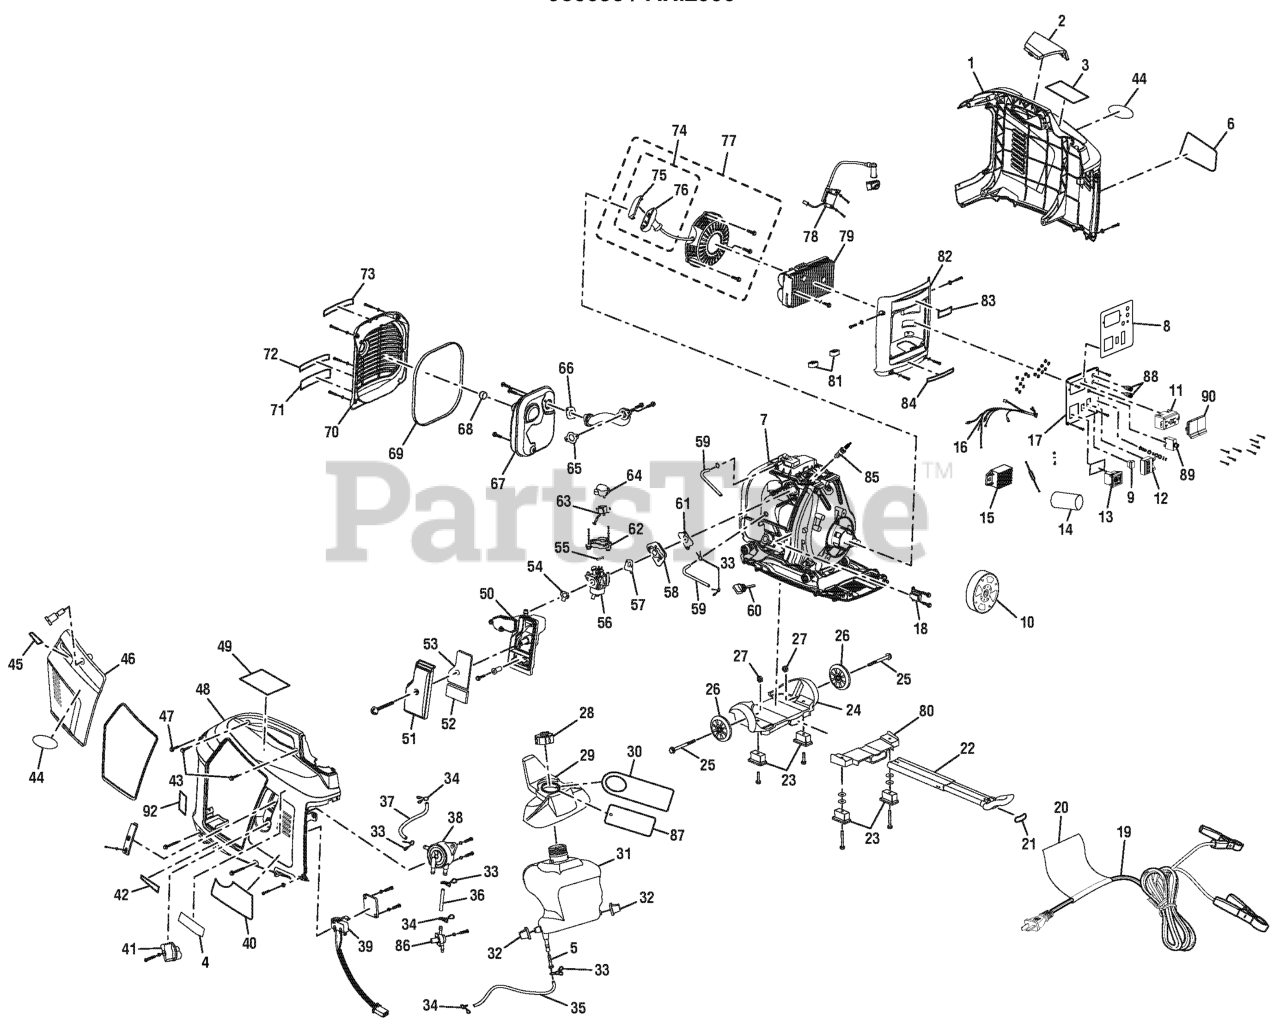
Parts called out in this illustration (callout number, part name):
1	RIGHT HOUSING
2	SPARK PLUG ACCESS COVER
3	E85 LABEL
4	FIRE DANGER LABEL
5	FUEL FILTER
6	FEATURES LABEL
8	CONTROL PANEL LABEL
9	AUTO IDLE SWITCH
10	STATOR ASSEMBLY
11	AC RECEPTACLE
12	IGNITION MODULE
13	DC RECEPTACLE
14	HEAT SHRINK TUBE
15	BRIDGE RECTIFIER
16	WIRING HARNESS (INTERNAL)
17	CONTROL PANEL
18	PICK-UP COIL
19	BATTERY CHARGING CABLE
20	CORD LABEL
21	HANDLE RELEASE LABEL
22	HANDLE ASSEMBLY
23	RUBBER FOOT
24	REAR HANDLE AND WHEEL BRACKET
25	WHEEL MOUNTING BOLT
27	HEX NUT (WHEEL MOUNTING)
28	FUEL CAP ASSEMBLY
29	FUEL OVERSPILL GUARD
30	HANGTAG (WARNING)
31	FUEL TANK
32	FUEL TANK SUPPORT
33	CLAMP (D9 X 1.2 MM)
34	CLAMP (D7 X 0.8 MM)
35	FUEL LINE (D4 X D8 X 260 MM)
36	FUEL LINE (D4 X D8 X 130 MM)
37	FUEL LINE (D4 X D8 X 170 MM)
38	FUEL PUMP
39	ENGINE SHUT OFF SWITCH
40	QUICK START LABEL
41	SWITCH HANDLE
42	LUBRICANT LABEL
43	BOLT (M6 X 30 MM)
44	LOGO LABEL
45	CHOKE LABEL
46	MAINTENANCE COVER
47	BOLT (M6 X 100 MM)
48	LEFT HOUSING
49	CPSC LABEL
50	AIR FILTER BACK
51	AIR FILTER COVER
52	AIR FILTER (LOWER)
53	AIR FILTER (UPPER)
54	INTAKE GASKE
55	GOVERNOR DAMPING SPRING
56	CARBURETOR ASSEMBLY
57	CARBURETOR GASKET
58	HEAT DAM INSULATOR
59	PULSE LINE (D7 X D11 X 160 MM)
60	DIPSTICK
61	INSULATOR GASKET
62	GOVERNOR BOTTOM COVER
63	GOVERNOR
64	GOVERNOR TOP COVER
65	MANIFOLD GASKET
66	MUFFLER GASKET
67	MUFFLER
68	SPARK ARRESTOR
69	MUFFLER COVER SEAL
70	MUFFLER COVER
71	DATA LABEL
72	COMBUSTION LABEL
73	HOT SURFACE LABEL
74	ROPE HANDLE ASSEMBLY
75	HANDLE COVER (ROPE)
76	ROPE HANDLE
77	RECOIL STARTER ASSEMBLY
78	IGNITION COIL
79	INVERTER MODULE
80	FOOT BRACE (FRONT HANDLE)
81	INVERTER MODULE SUPPORT
82	CONTROL PANEL HOLDER
83	LOGO LABEL (SMALL)
84	GROUND WARNING LABEL
85	SPARK PLUG
86	FUEL SHUT OFF VALVE
87	HANGTAG (INSTRUCTIONS)
88	PARALLEL PLUG
89	CIRCUIT BREAKER (20 AMP)
90	RECEPTACLE COVER
